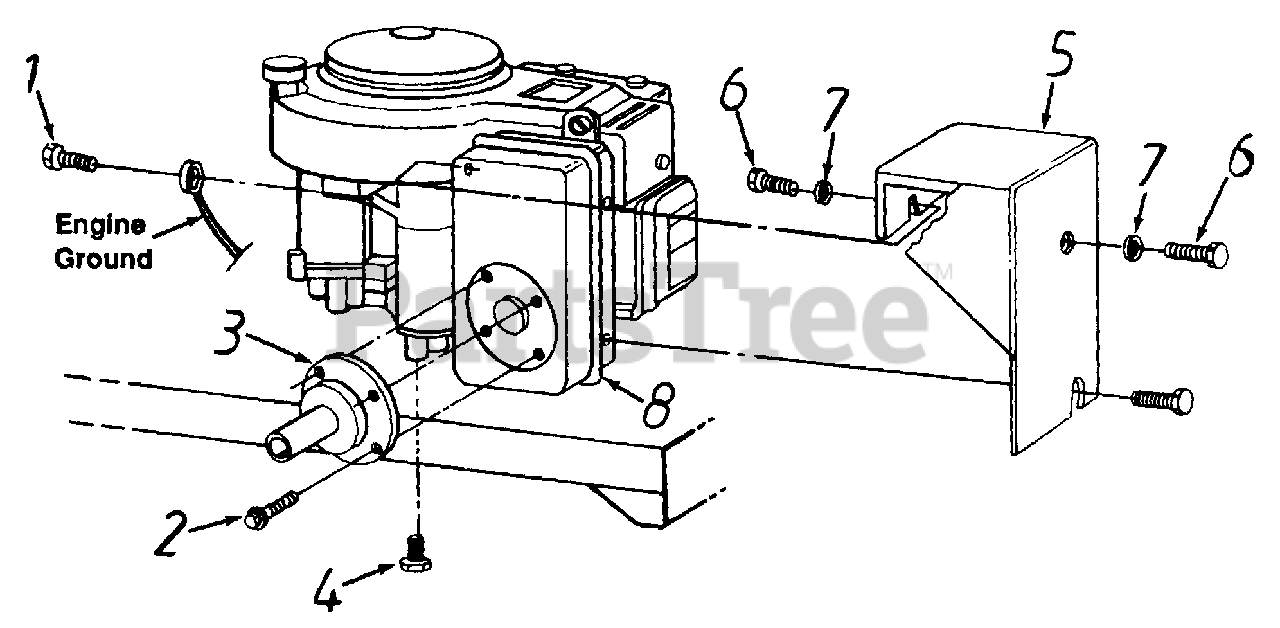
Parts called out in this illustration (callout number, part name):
1	Hex Bolt M6-1" x 10 MM Lg. (Gr. 5)
2	Hex Wash. Hd. F-Tap Scr. #8-32 x .38" Lg.
3	Exhaust Pipe Ass'y.
4	Hex L-Wash. Tl-Tap Scr.3/8-16 x 1" Lg.
5	Muffler Heat Shield Ass'y.
6	Hex Cap Scr. M6-1" x 14 MM Lg.
7	Bell-Wash..265" I.D. x .75" O.D.
8	Muffler - Supplied by Engine Manufacturer
